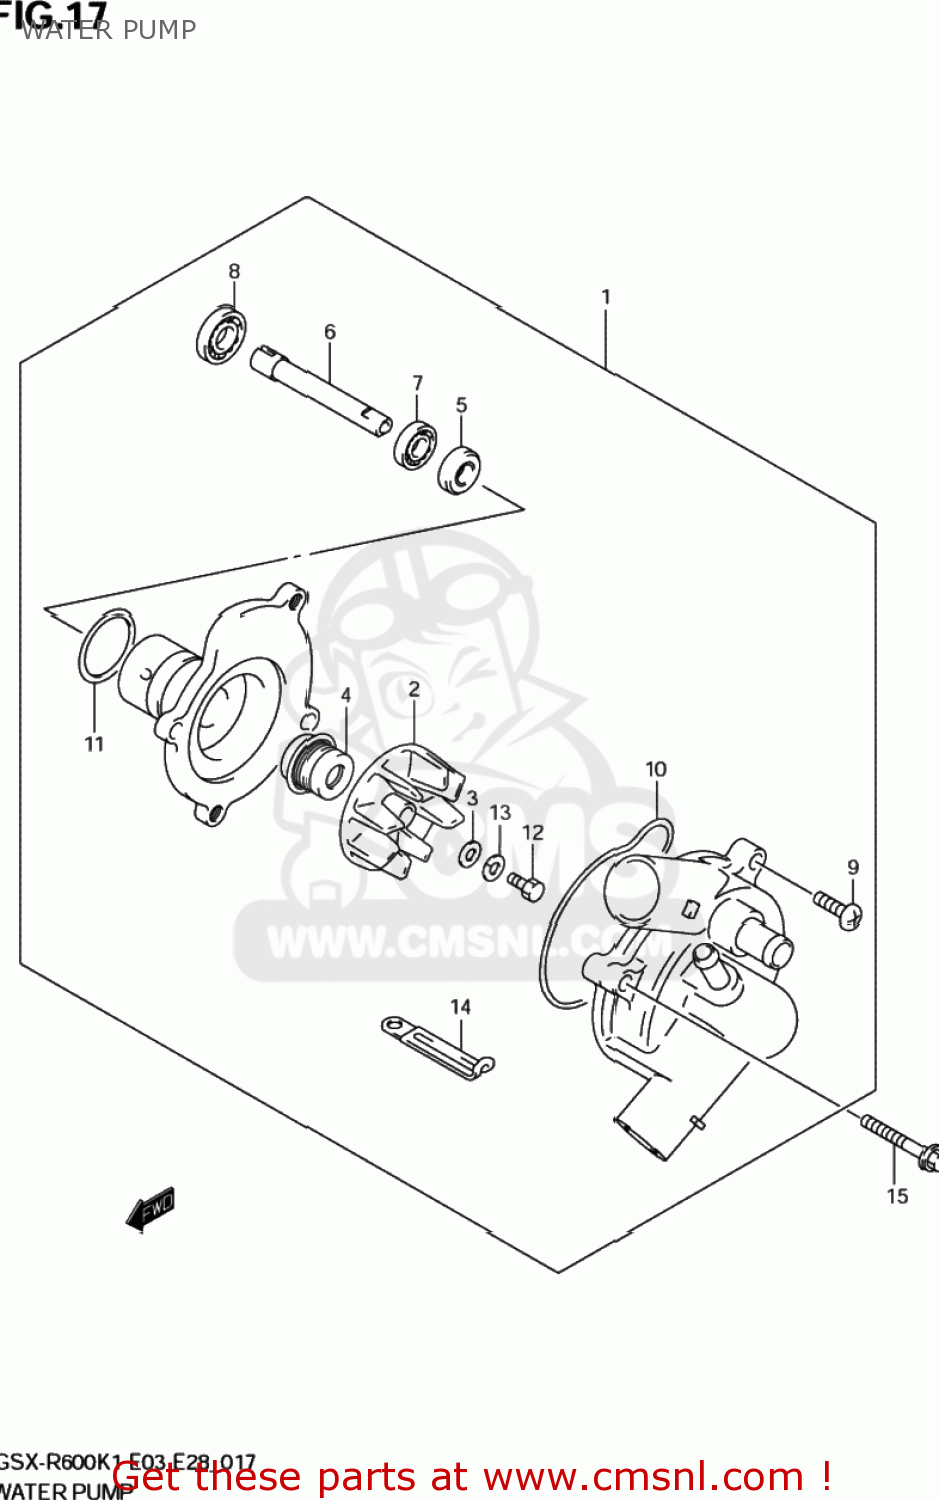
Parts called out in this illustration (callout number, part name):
1	PUMP ASSY,WATE
2	IMPELLER
3	GASKET(6X15X2.2) (NAS)
4	SEAL,MECHANICAL
5	SEAL,OIL(10X21X5)
6	SHAFT
7	BEARING(10X26X8)
8	BEARING(12X28X8)
9	SCREW 6X16
10	O RING
11	O RING,WATER PUMP HOLDER
12	BOLT(6X13)
13	WASHER
14	CLAMP(L:65)
15	BOLT
